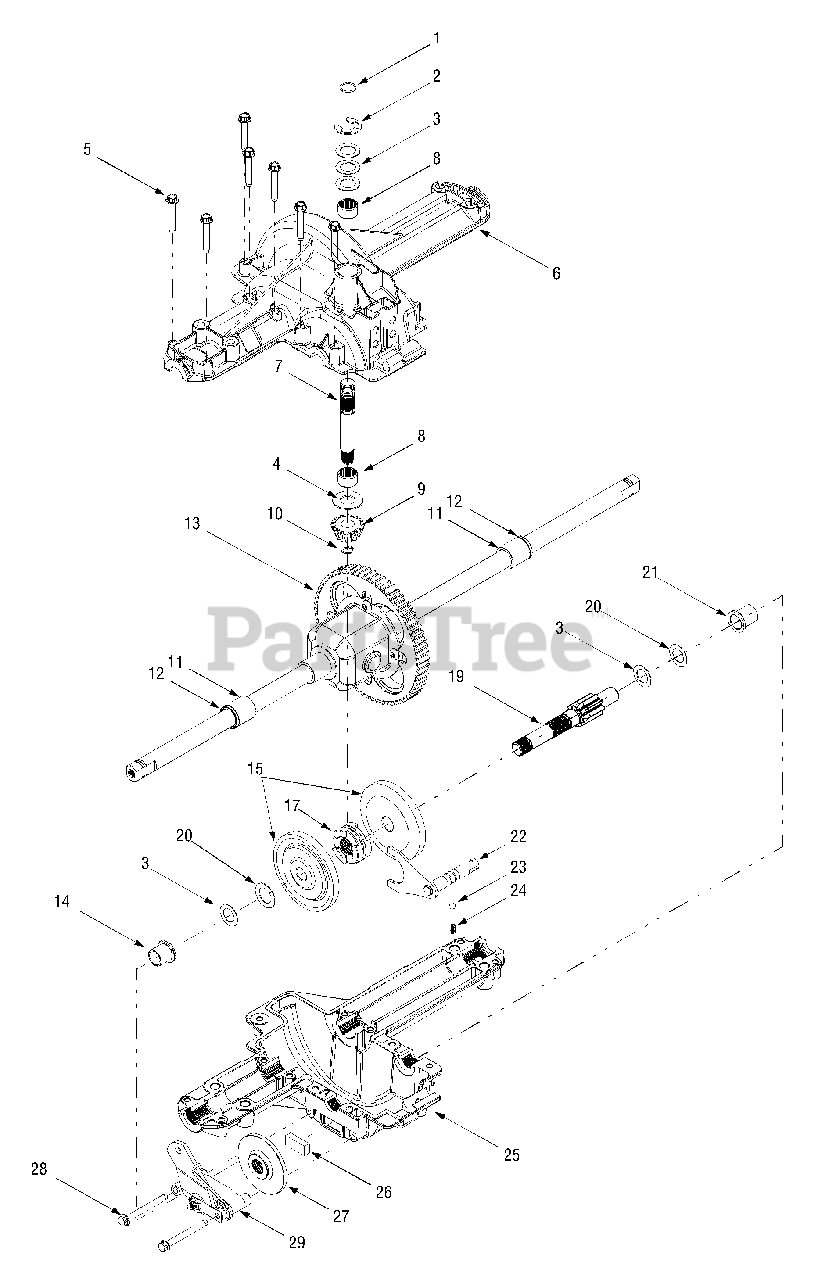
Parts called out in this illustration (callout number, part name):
1	Ring, Wire
2	Ring, E Type,.750
3	Flat Washer, 5/8 x 1.0 x.030
4	Washer, Thrust.635 x 1.26 x.06
5	Self-tapping Screw, 1/4-20 x 1.625
6	Upper Housing
7	Input Shaft
8	Needle Bearing,.625 x.813 x.495
9	14-tooth Bevel Pinion
10	Retaining Ring,.437
11	Sleeve Bearing,.75 x.1.0 x 1.0
12	Seal,.75 x 1.0 x.125
13	Differential Assembly
14	Flange Bearing, 5/8 x 3/4 x 3/4
15	42-tooth Bevel Gear
17	Clutch Collar
19	Drive Shaft
20	Thrust Washer, 1.0 x.632 x.0
21	Flange Bearing, 5/8 x 3/4 x 15/16
22	Detent Shaft Assembly
23	Detent Ball
24	Compression Spring
25	Lower Housing
26	Brake Puck
27	Brake Disc
28	Self-tapping Screw, 1/4-20 x 2.375
29	Brake Assembly
